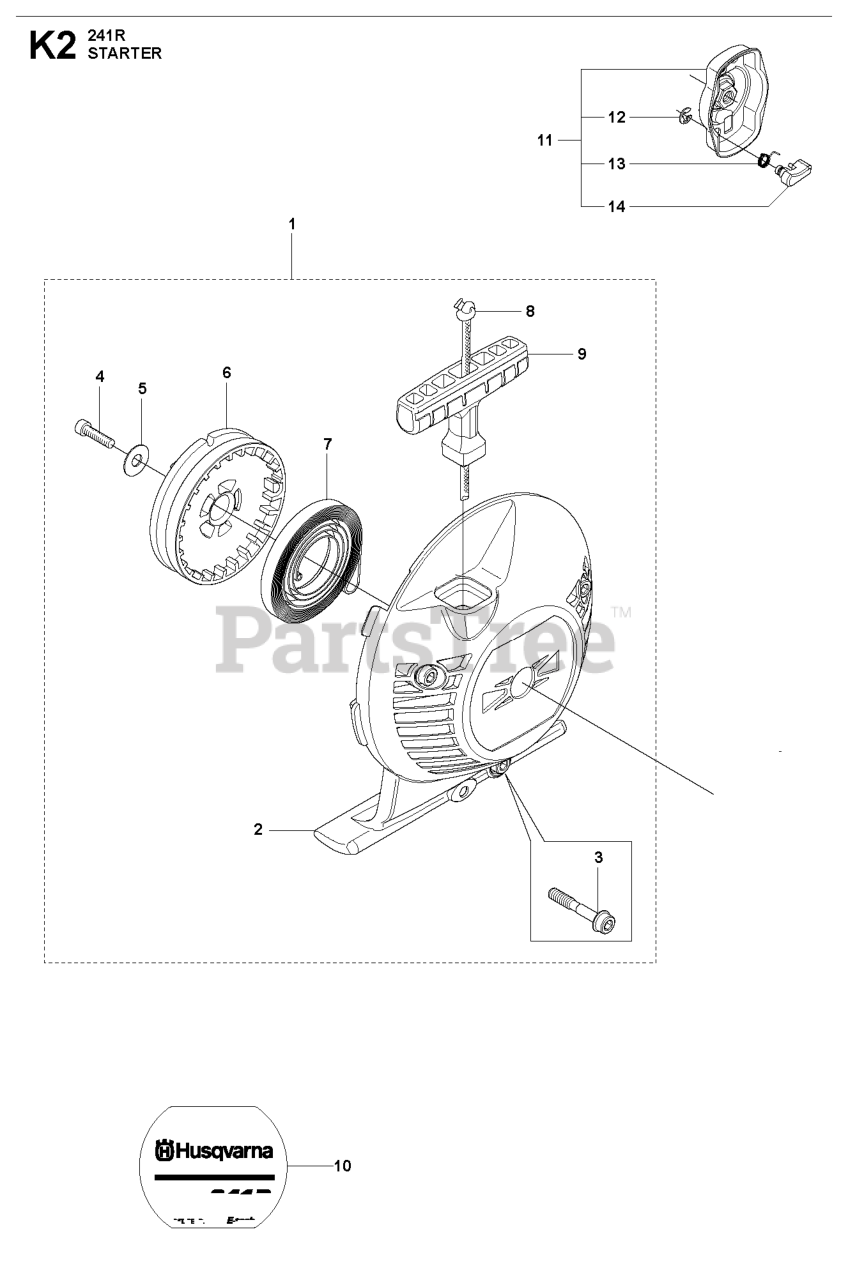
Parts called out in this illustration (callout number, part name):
2	STARTER
3	SCREW IHSCFMO
6	STARTER PULLEY
7	STARTER SPRING
8	STARTER ROPE
9	STARTER HANDLE
11	PAWL
14	STARTER PAWL
